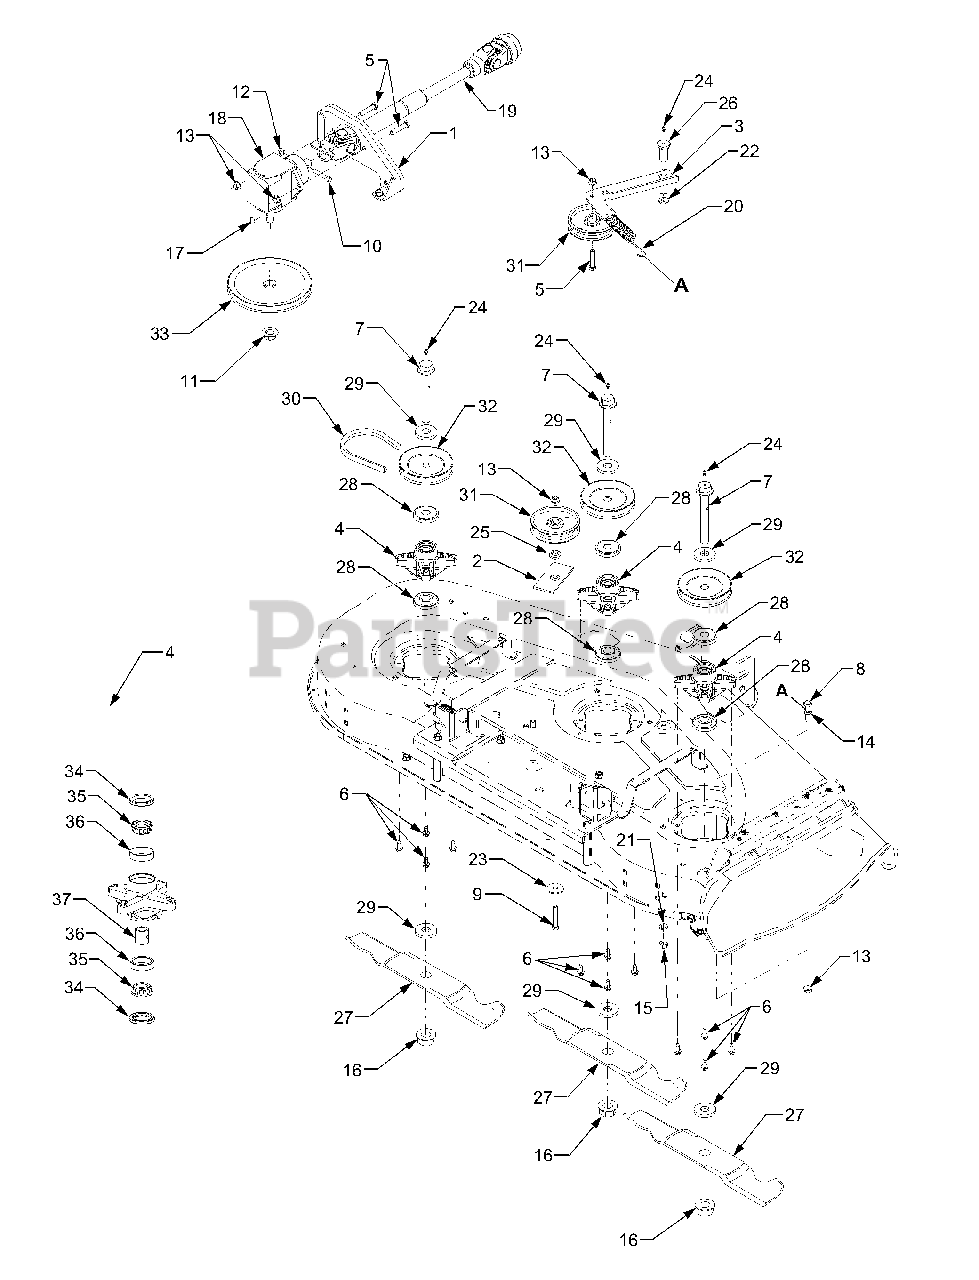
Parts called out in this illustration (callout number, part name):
1	Bracket, Drive
2	Assembly, Spacer
3	Bracket, Idler
4	Assembly, Spindle - Replaces all older spindles.
5	Screw, Hex Cap 3/8-16 x 1.75 GR5
6	Screw, Hex Wash Hd Tapp 5/16-18 x 1.0
7	Bolt, Spindle, 3/4-16 x 5.37 Mfg. Code 1I224G & before
7	Bolt, Spindle, 3/4-16 x 5.215 Mfg. Code 1I234G & after
8	Screw,Hex Cap 3/8-16 x 1.25 GR5
9	Screw, Hex Cap 3/8-16 x 2.75 GR5
10	Screw, Sock. Hd. 5/16-18 x 1.75
11	Nut , Hex Flanged 5/8-18
12	Nut, Hex Lock 5/16 -18
13	Nut, Flange Lock 3/8-16
14	Nut, Hex Lock, 3/8-16
15	Nut, Hex 7/16-14
16	Nut, Hex Flange, 3/4-16
17	Key, Hi-Pro
18	Drive, Right Angle
19	Shaft, Drive
19	Half Shaft, Front Only
19	Half Shaft, Rear Only
20	Spring, Extension 6.5" Lg.
21	Washer, Lock 7/16" I.D.
22	Washer, Flat .47" I.D. x .88" OD
23	Washer, Flat .406" I.D.
24	Fitting, Grease
25	Spacer, Shoulder
26	Bolt, Shoulder .68" Dia. x 1.59
27	Blade, High Lift 18.5" Lg.
27	Blade, Hard Coated
28	Spacer, Deck Spindle
29	Spacer, Blade
30	Belt, “V" 117" Lg.
31	Pulley, Flat
32	Pulley, “V"
33	Pulley, Drive
34	Seal, Oil
35	Bearing, Cone - Mfg. Code 1I173G and before
35	Bearing, Cone - Mfg Code 1I183G and after
36	Cup, Bearing - Mfg. Code 1I173G and before
36	Cup, Bearing - Mfg. Code 1I183G and after
37	Spacer, Bearing - Mfg. Code 1I173G and before
37	Spacer, Bearing - Mfg. Code 1I183G and after
